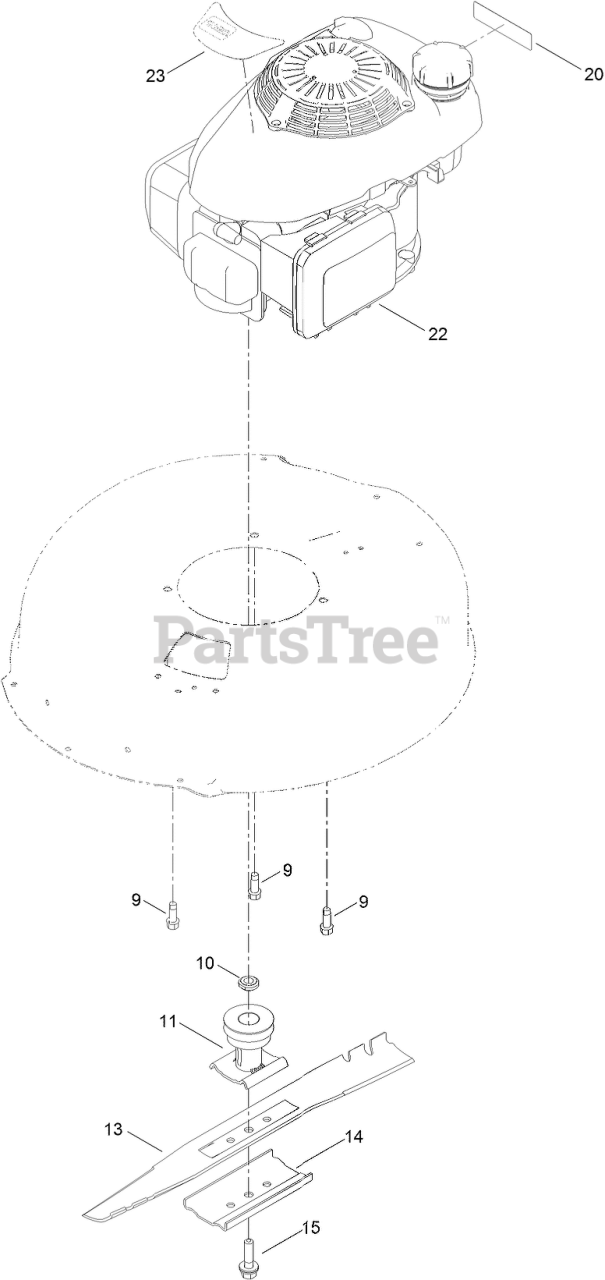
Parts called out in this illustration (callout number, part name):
9	SCREW-TAPTITE
10	SPACER-DRIVER
11	DRIVER-BLADE
13	BLADE-21IN
14	SUPPORT-BLADE
15	BOLT-BLADE
20	DECAL-ARRESTOR, SPARK
23	DECAL-SHROUD, HONDA
